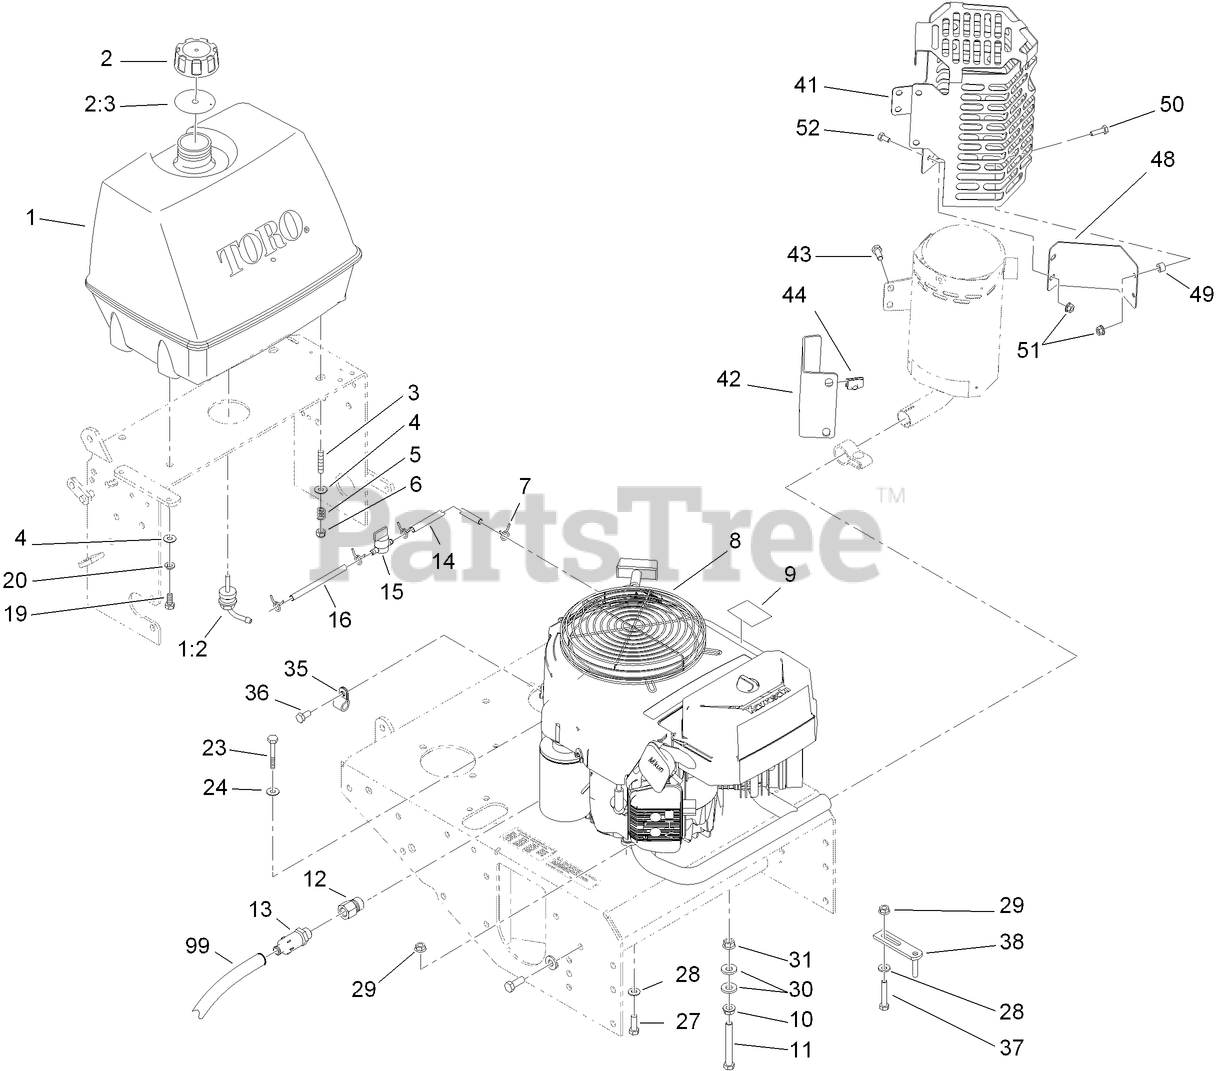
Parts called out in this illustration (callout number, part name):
1	FUEL TANK ASM
1:2	FITTING-FUEL, BULKHEAD
2	GAS CAP ASM
2:3	GASKET-CAP, GAS
4	WASHER-PLAIN
5	SPRING-TANK, FUEL
6	NUT-LOCK, NI
9	DECAL-WARNING
10	NUT-HHF, WHIZ
11	SCREW-HH
12	Adapter
13	VALVE-DRAIN, OIL
14	HOSE-FUEL
15	VALVE-FUEL
16	HOSE-FUEL
19	SCREW-HH
20	WASHER-LOCK
23	SCREW-HH
24	WASHER-LOCK
27	SCREW-HH
28	WASHER-SPRING
29	NUT-HF
30	WASHER-BELLEVILLE
31	NUT-HF
35	Clip-Loom
36	SCREW-HH
37	SCREW-HH
38	GUIDE-BELT
41	MUFFLER SHIELD ASM
42	BRACKET-MUFFLER
43	SCREW-HH
44	NUT-U
48	BAFFLE-MUFFLER SHIELD
49	SPACER
50	SCREW-HH
51	NUT-HHF
52	SCREW-HH
99	HOSE-DRAIN, OIL
